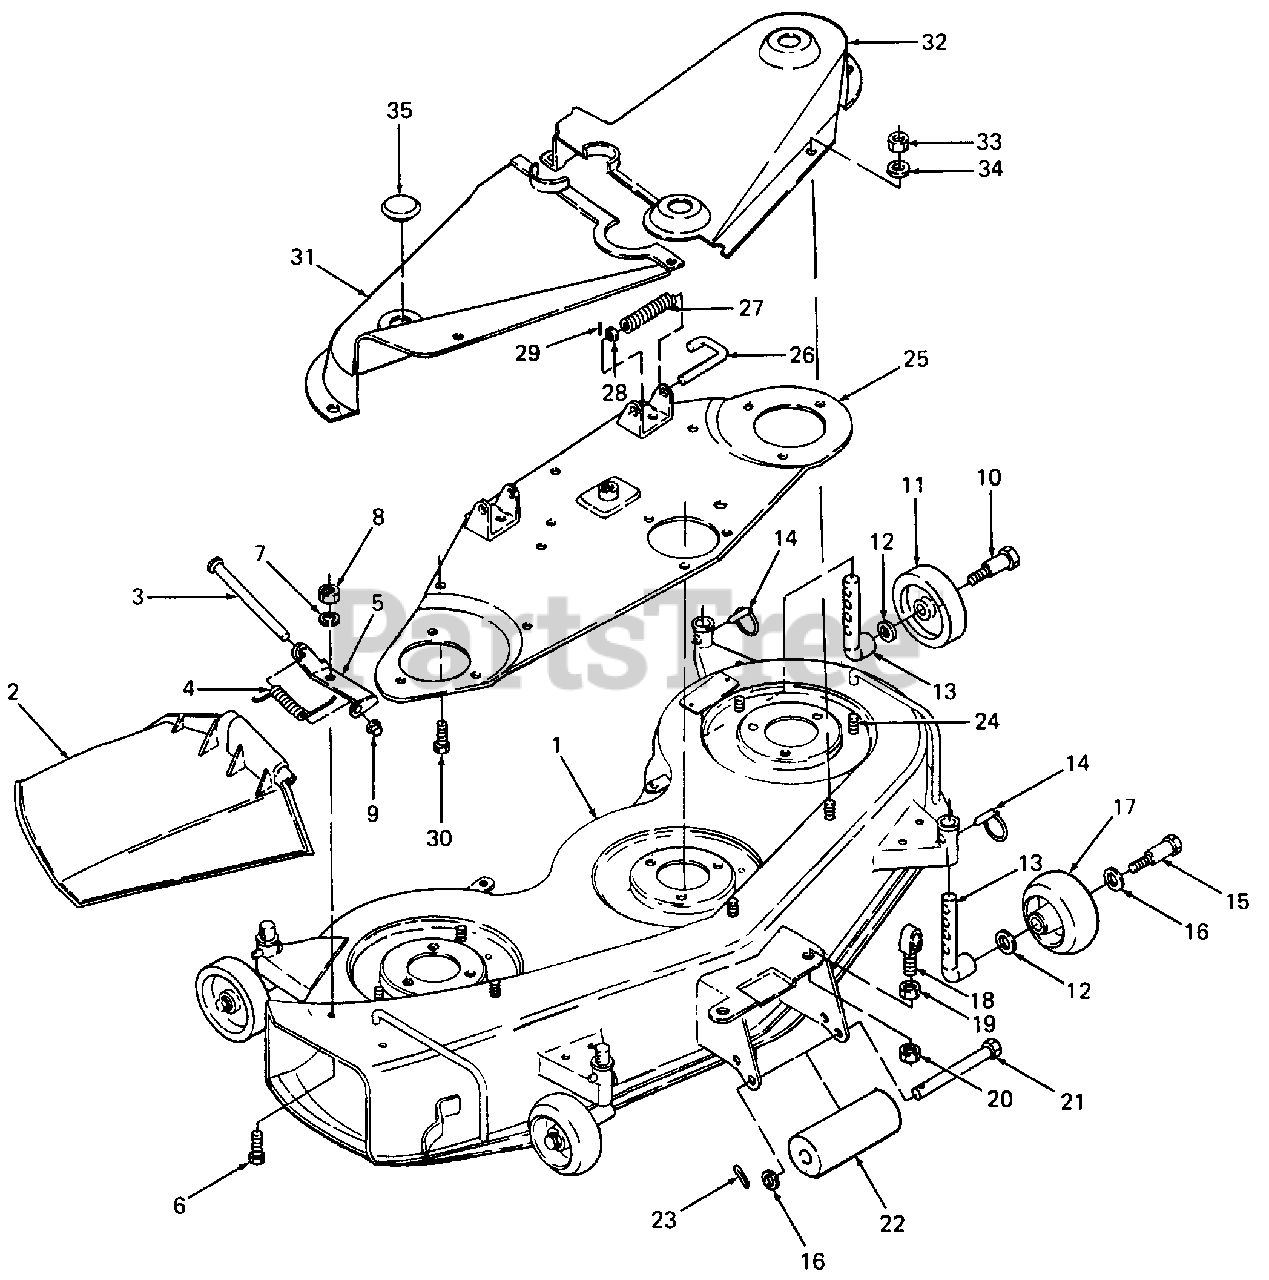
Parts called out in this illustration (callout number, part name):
2	Chute Kit w/Graphic
3	Pin, Hinge, 0.25 Dia X 6.75 Lg
4	Spring, Torsion
5	Bracket, Hinge Mtg
6	Screw, Truss Machine, 1/4-20 X .75 Lg, Phillips
7	Washer, Lock, 1/4 Dia
8	Nut, Hex, 1/4-20 GR5
9	Nut, Cap Speed
10	Screw, Shoulder
11	Wheel, Gauge, 5 in. Dia
12	Washer, Bell
13	Axle, Deck
14	Pin, Clevis w/Detent Ball
15	Screw, Shoulder
16	Washer, Flat, .510 X 1.0 X .06 Thk
17	Wheel, Ball w/Fitting, 5 in. DIA
18	Hanger, Front Mower Support
19	Nut, Hex Jam, 5/8-11 GR5
20	Nut, Hex Insert Top Lock, 5/8-11 GR5
21	Pin, Clevis, 1/2 Dia X 7.0 Lg
22	Roller, Front
23	Pin, Cotter, 3/16 Dia X 1.0 Lg
24	Screw, Hex Cutting, 5/16-18 X .75 Lg
25	Plate, Adapter
26	Pin, Mower Support
27	Spring, Compression
28	Washer, Flat, .531 X .930 X .050 Thk
29	Pin, Spirol Spring, 3/16 Dia X .75 Lg
30	Screw, Hex Cutting, 5/16-18 X .75 Lg
31	Cover, Belt RH (White)
32	Cover, Belt LH (White)
33	Nut, Hex, 5/16-18 GR5
34	Washer, Flat, .34 X .88 X .062 Thk
35	Plug, Button
